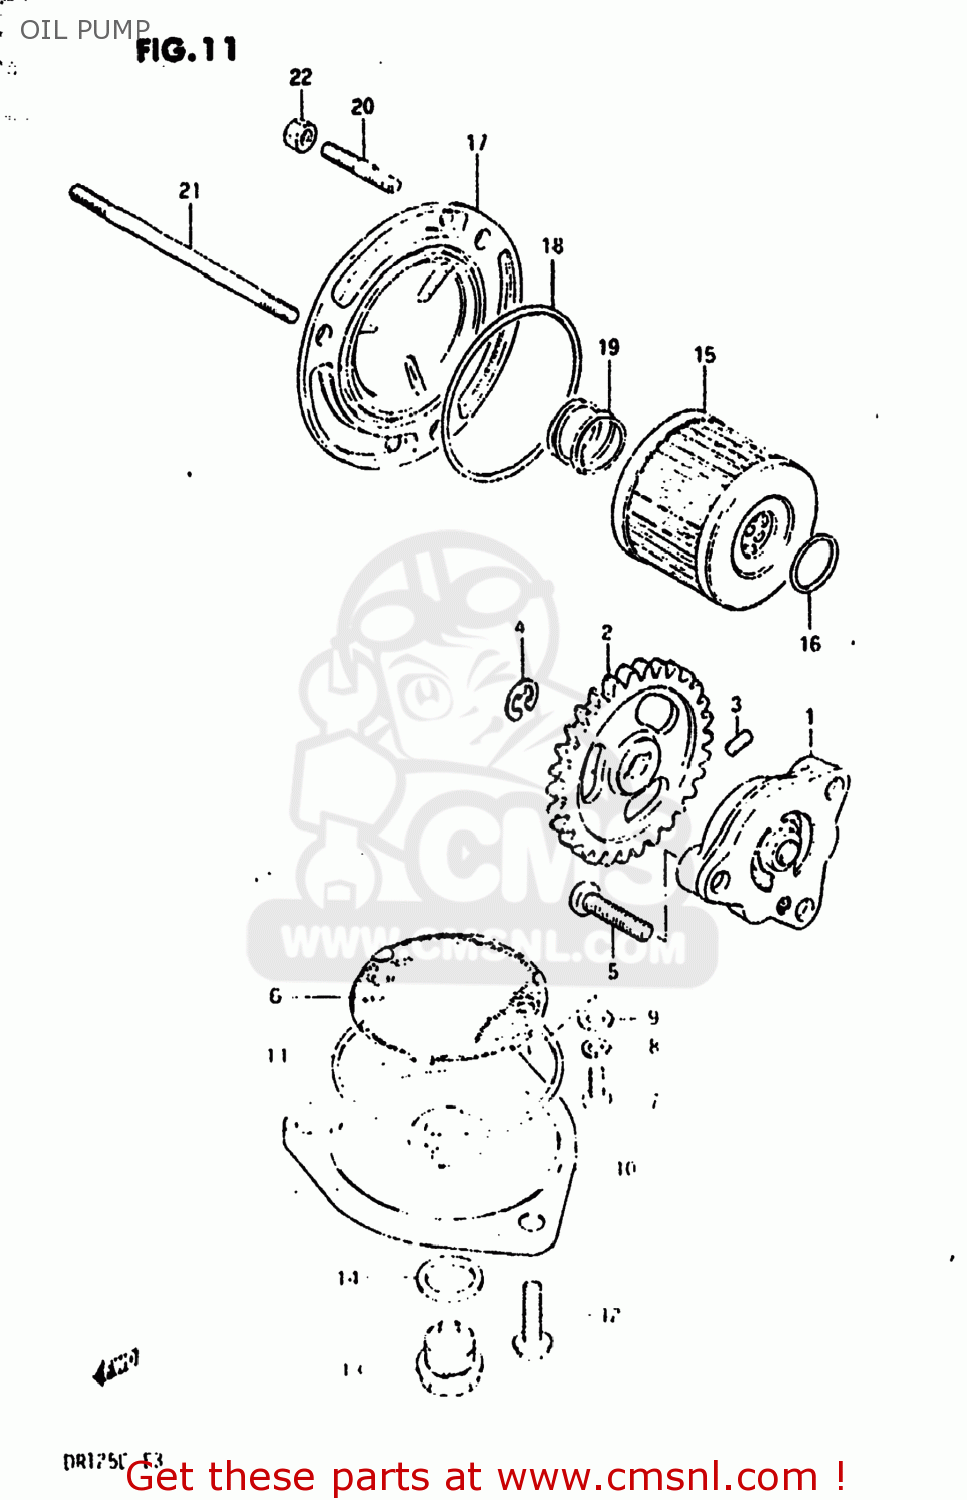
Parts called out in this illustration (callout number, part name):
1	PUMP ASSEMBLY,OIL
2	GEAR,ENG OIL PUMP DRIVEN(NT:30
3	PIN(2.5X11.8)
4	WASHER 6MM
5	SCREW
6	STRAINER,ENGINE OIL
7	SCREW
8	LOCK WASHER
9	WASHER
10	CAP,OIL STRAINER
11	O RING(D:2.4,ID:60.5)
12	BOLT (6X20)
13	PLUG
14	GASKET(14X19.2X2) (NAS)
15	FILTER ASSY,ENGINE OIL
16	O RING(D:1.9,ID:13)
17	CAP,OIL FILTER
18	O RING(D:2.4,ID:52.6)
19	SPRING
20	STUD 6X12
21	STUD BOLT, 6X8
22	NUT 6MM
